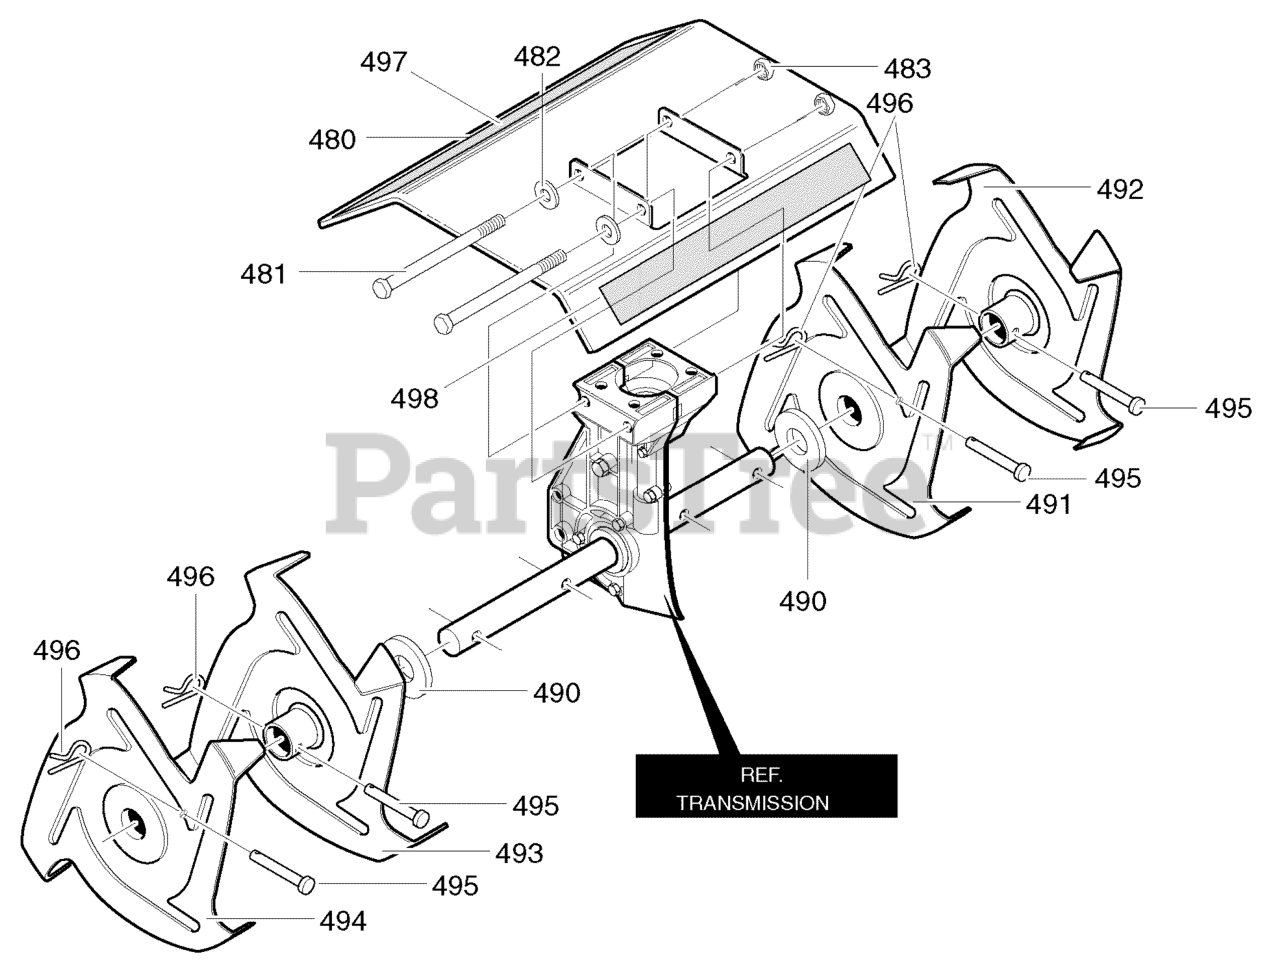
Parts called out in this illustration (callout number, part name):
480	Shield, Tine
481	Screw, 1/4-20x5.50
482	Washer
483	Nut, 1/4-20
490	Washer, Felt
491	Tine Assy. Inner LH
492	Tine Assy. Outer LH
493	Tine Assy. Inner RH
494	Tine Assy. Outer RH
495	Clevis Pin
496	Hair Pin
497	Decal, Caution
498	Decal, Tine Shield
